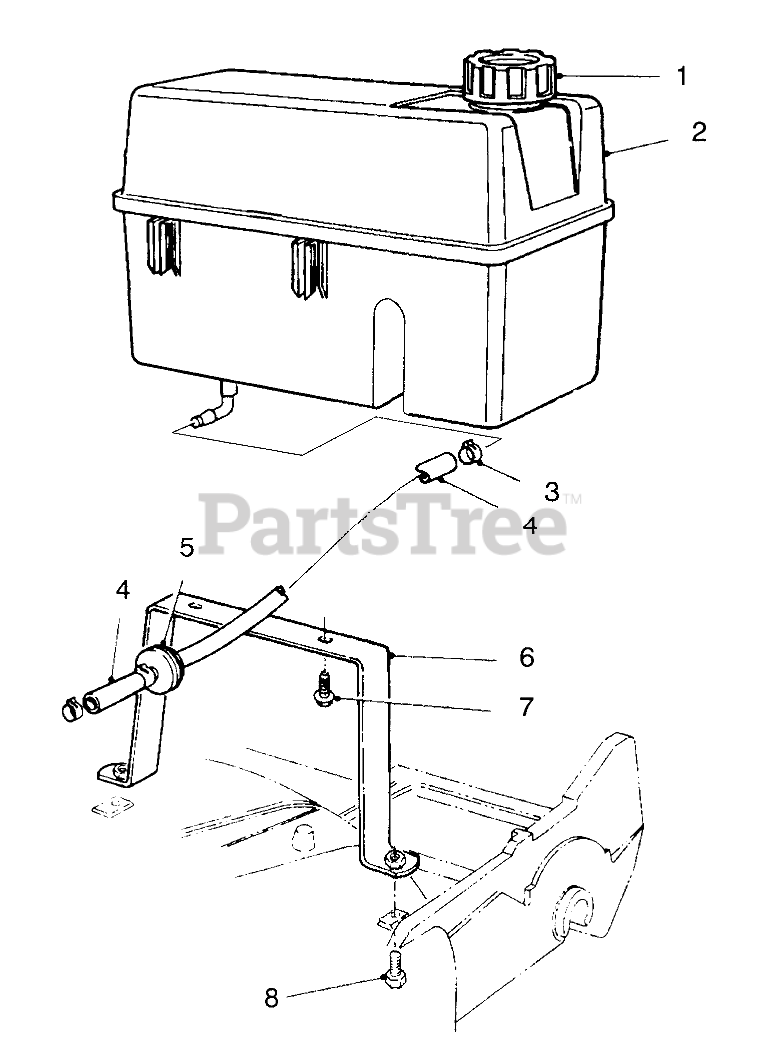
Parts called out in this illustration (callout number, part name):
1	GAS CAP ASM
2	TANK - FUEL
3	CLAMP-FUEL LINE
4	HOSE-FUEL
5	FILTER-FUEL
6	Wa-Base
7	SCREW-HWH
8	SCREW-HH
